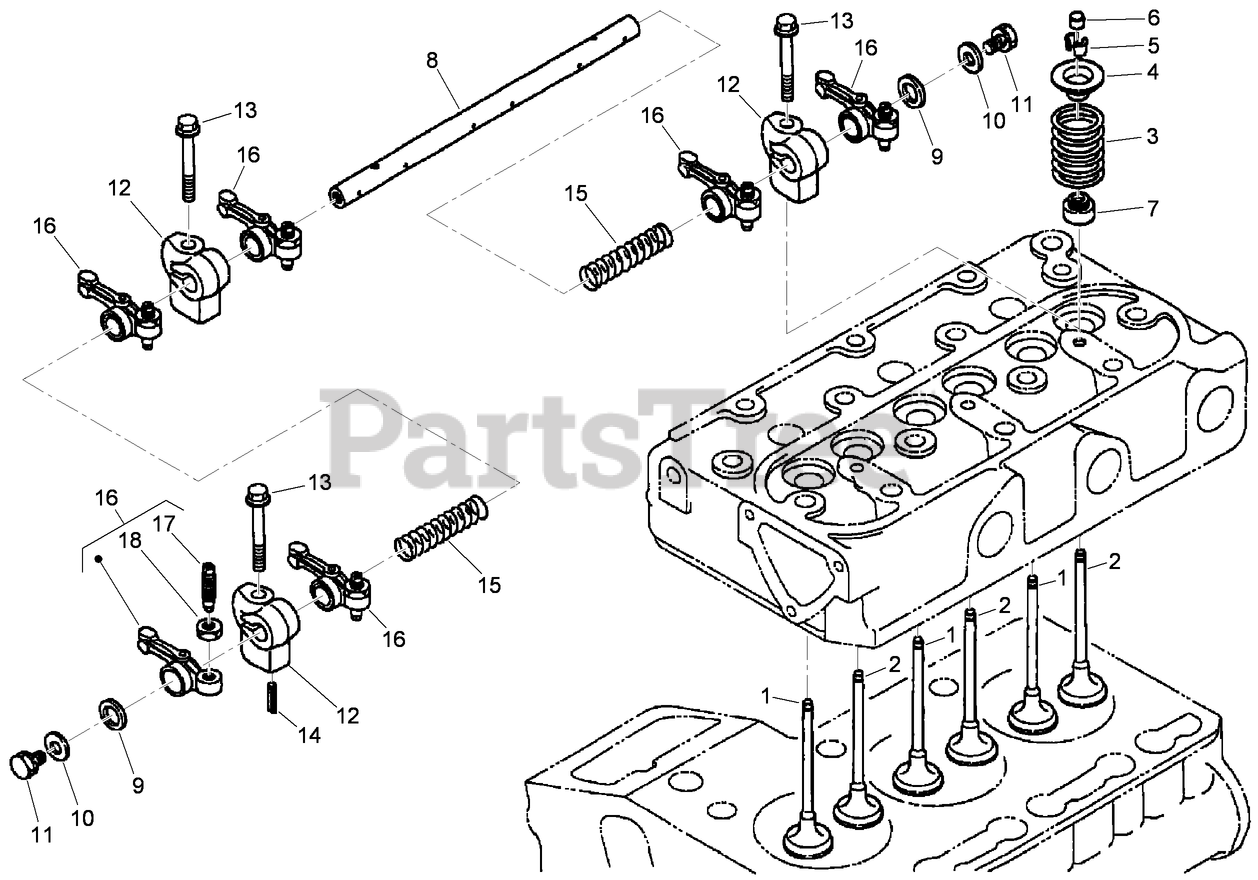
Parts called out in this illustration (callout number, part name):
1	VALVE-INLET
2	VALVE-EXHAUST
3	SPRING-VALVE
4	RETAINER-SPRING, VALVE
5	COLLET-SPRING, VALVE
6	CAP-VALVE
7	SEAL-STEM, VALVE
8	SHAFT-ARM, ROCKER
9	WASHER
10	WASHER-PLAIN
12	BRACKET-ARM, ROCKER
13	BOLT-FLANGE
14	PIN-SPRING
15	SPRING
16	ROCKER ARM ASM
17	SCREW-ADJUSTING
